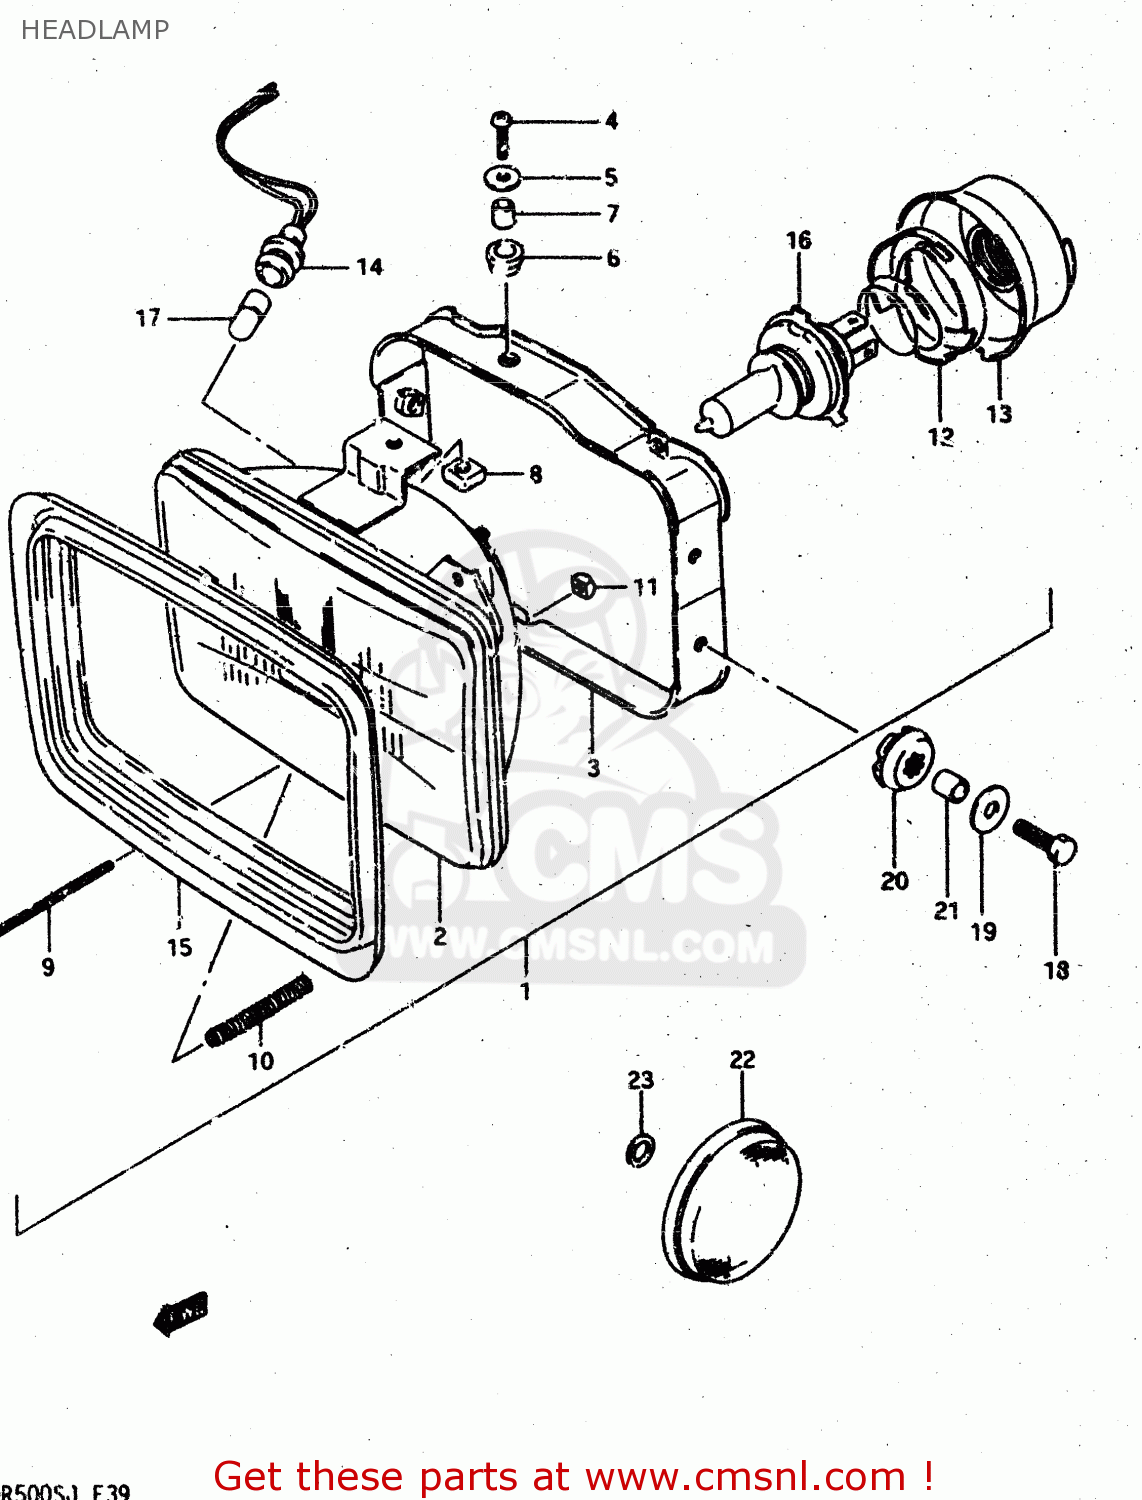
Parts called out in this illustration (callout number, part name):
1	HEADLAMP ASSY
2	UNIT
3	HOUSING
4	SCREW 5X20
5	WASHER
6	CUSHION
7	SPACER
8	NUT
9	SCREW,HEADLAMP ADJUST
10	SPRING
11	NUT
12	HOLDER,BULB
13	COVER,SOCKET
14	SOCKET,PARKING
15	SHADE
16	BULB(12V60/55W,H4)
17	BULB(12V4W)
18	BOLT
19	WASHER (6.5X20X1.2)
20	CUSHION
21	SPACER (6.8X10X10)
22	REFLECTOR,REFLEX FR
23	LOCK WASHER
